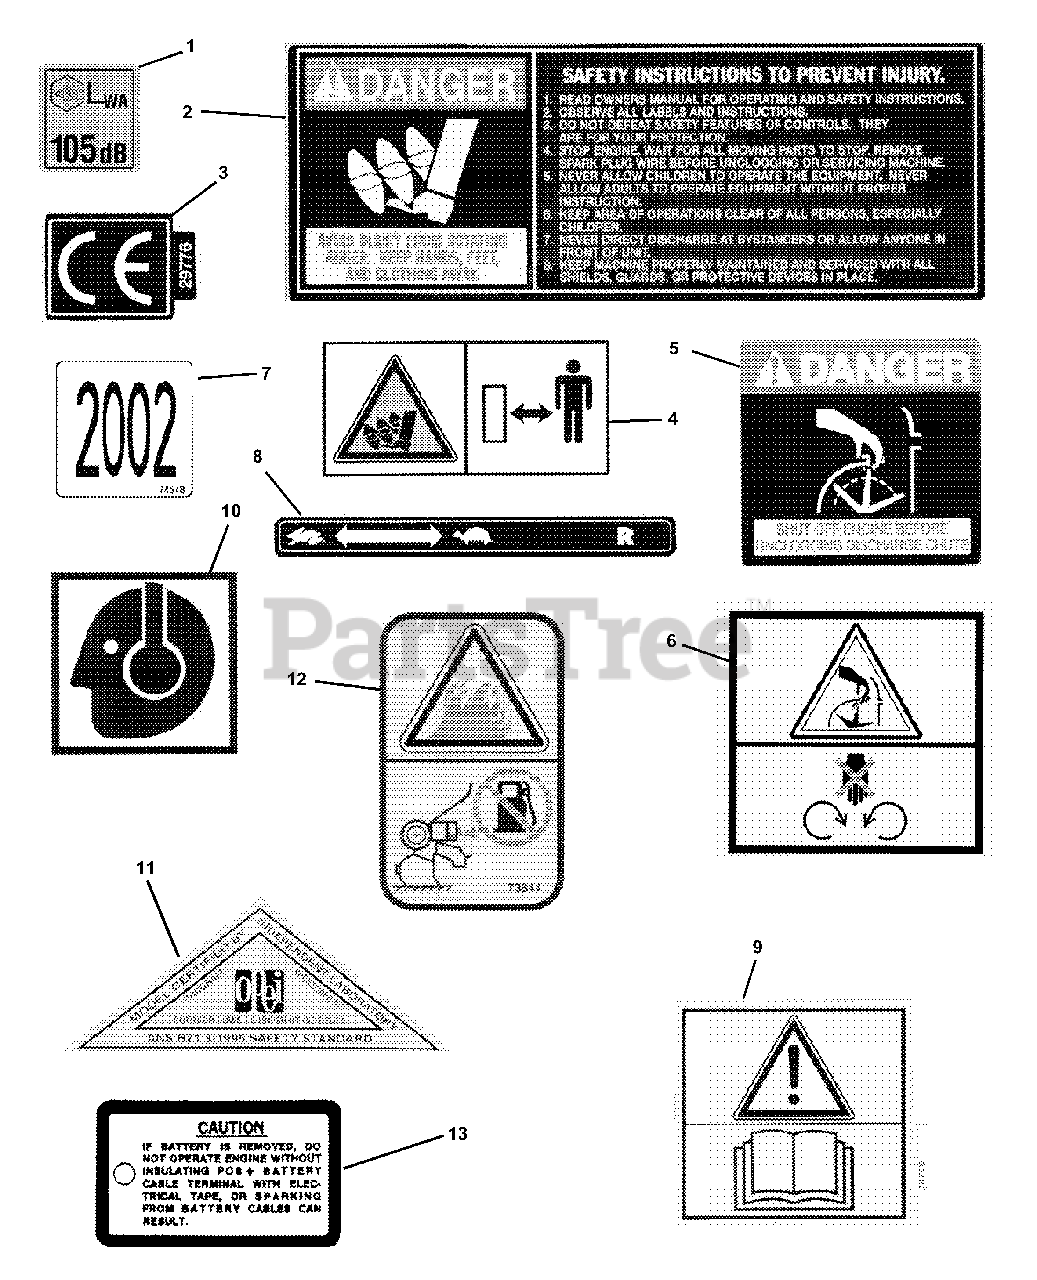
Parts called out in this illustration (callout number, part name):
1	DECAL, Noise Control (Euro)
2	DECAL, Foot Danger/Blank
3	DECAL, European Community (CE)
4	DECAL, Foot Danger (Euro)
5	DECAL, Hand Danger
6	DECAL, Chute (Euro)
7	DECAL, 2002 Year of Manufacture
8	DECAL, Gear Snow (Direction Control)
9	DECAL, Chute/Read Manual (Euro)
10	DECAL, Ear Protection
11	DECAL, OPEI Snow
12	DECAL, Fuel Safety
13	DECAL, Caution Tag
